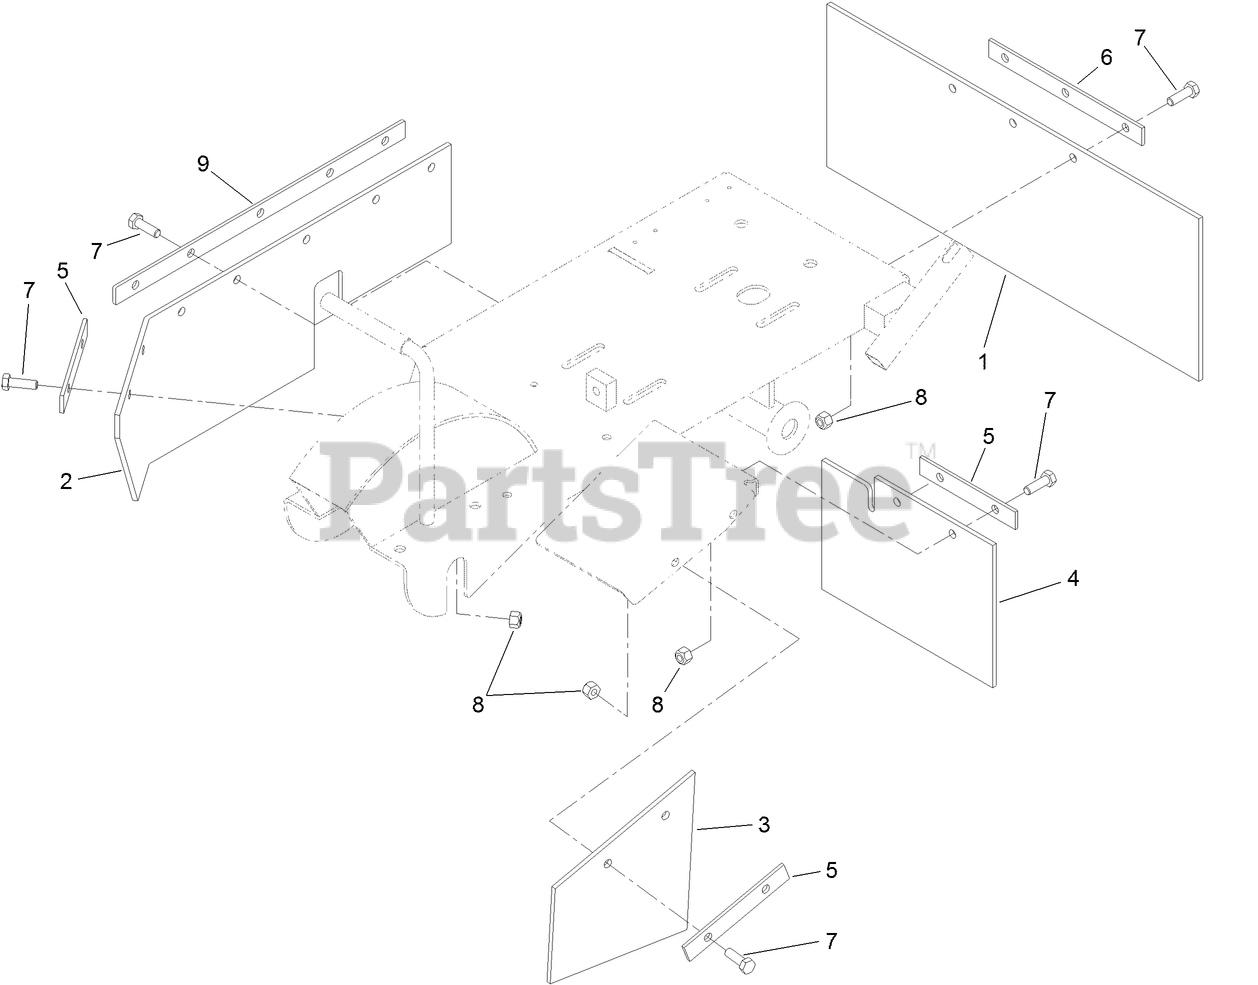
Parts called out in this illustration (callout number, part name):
1	FLAP-REAR
2	FLAP-RIGHT
3	FLAP-WING
4	FLAP-WING, REAR
5	PLATE-MOUNTING, FLAP
6	BRACKET-SUPPORT, FLAP
7	SCREW-HH
8	NUT-LOCK, NI
9	PLATE-MOUNTING, FLAP
